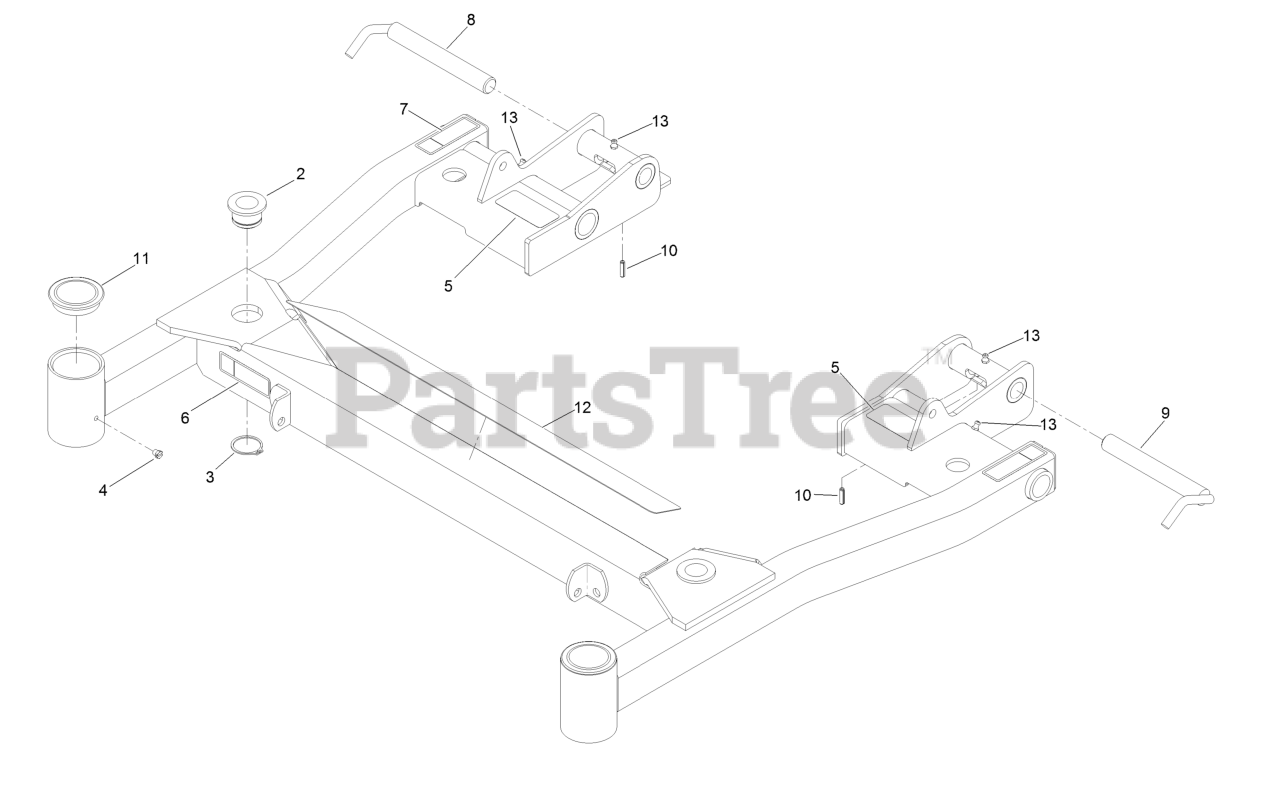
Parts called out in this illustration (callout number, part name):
2	Bushing-Support, Deck
3	Ring-Retaining
5	Decal-Warning
6	Decal-Danger
7	Decal-Warning, Folding Deck
8	Lock-Deck, RH
9	Lock-Deck, LH
10	Pin-Spring
11	Cap-Grease
12	Pad-Anti Skid
13	Fitting-Grease
